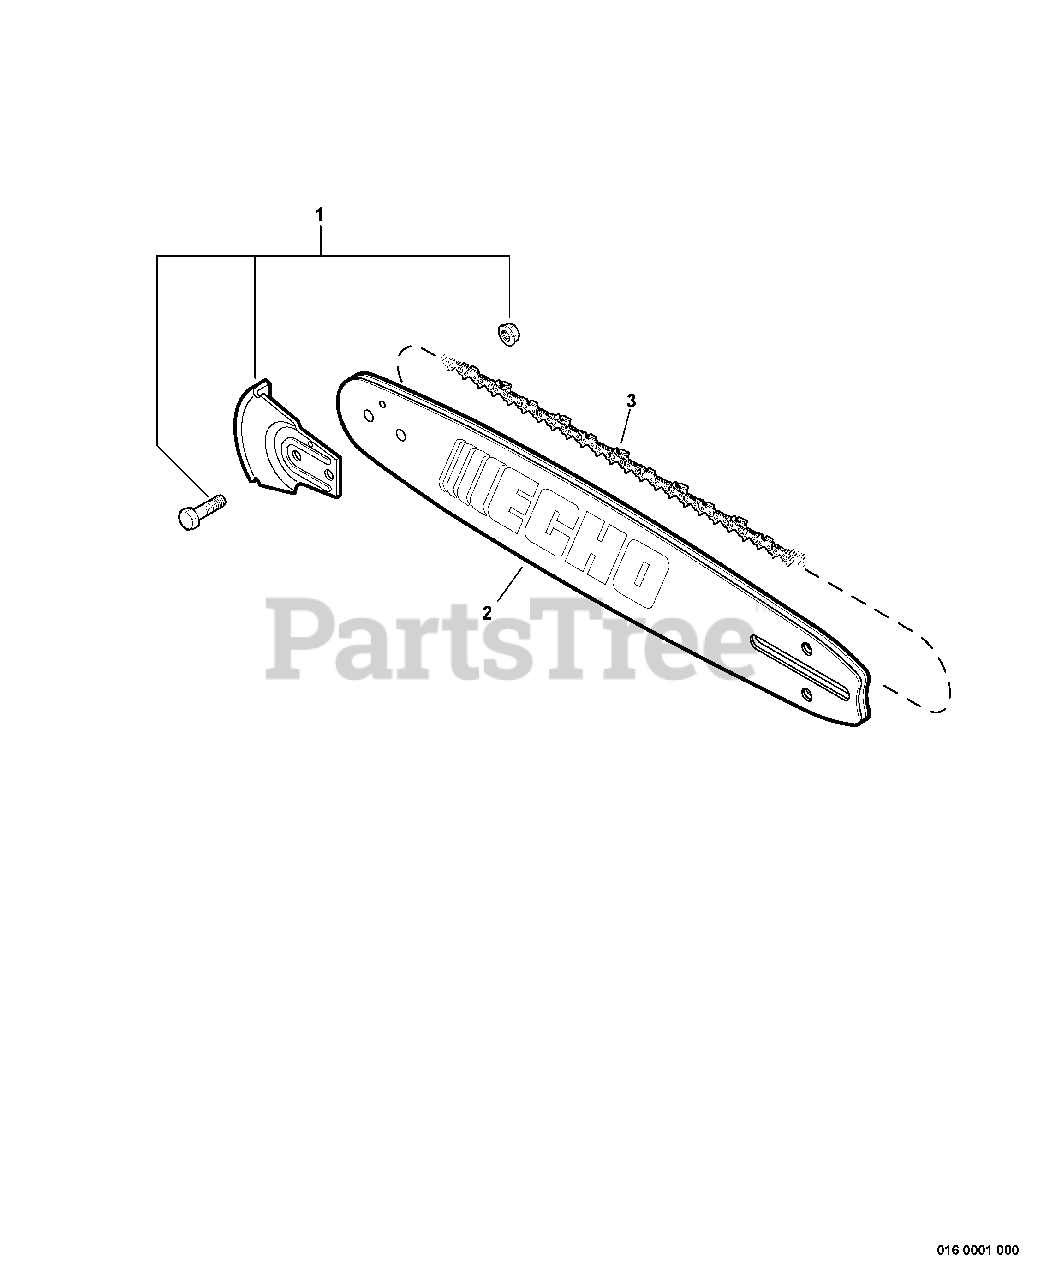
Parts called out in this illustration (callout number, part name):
1	KICK GUARD KIT
2	GUIDE BAR - 14" (35cm)
3	SAW CHAIN - 14" (35cm)
